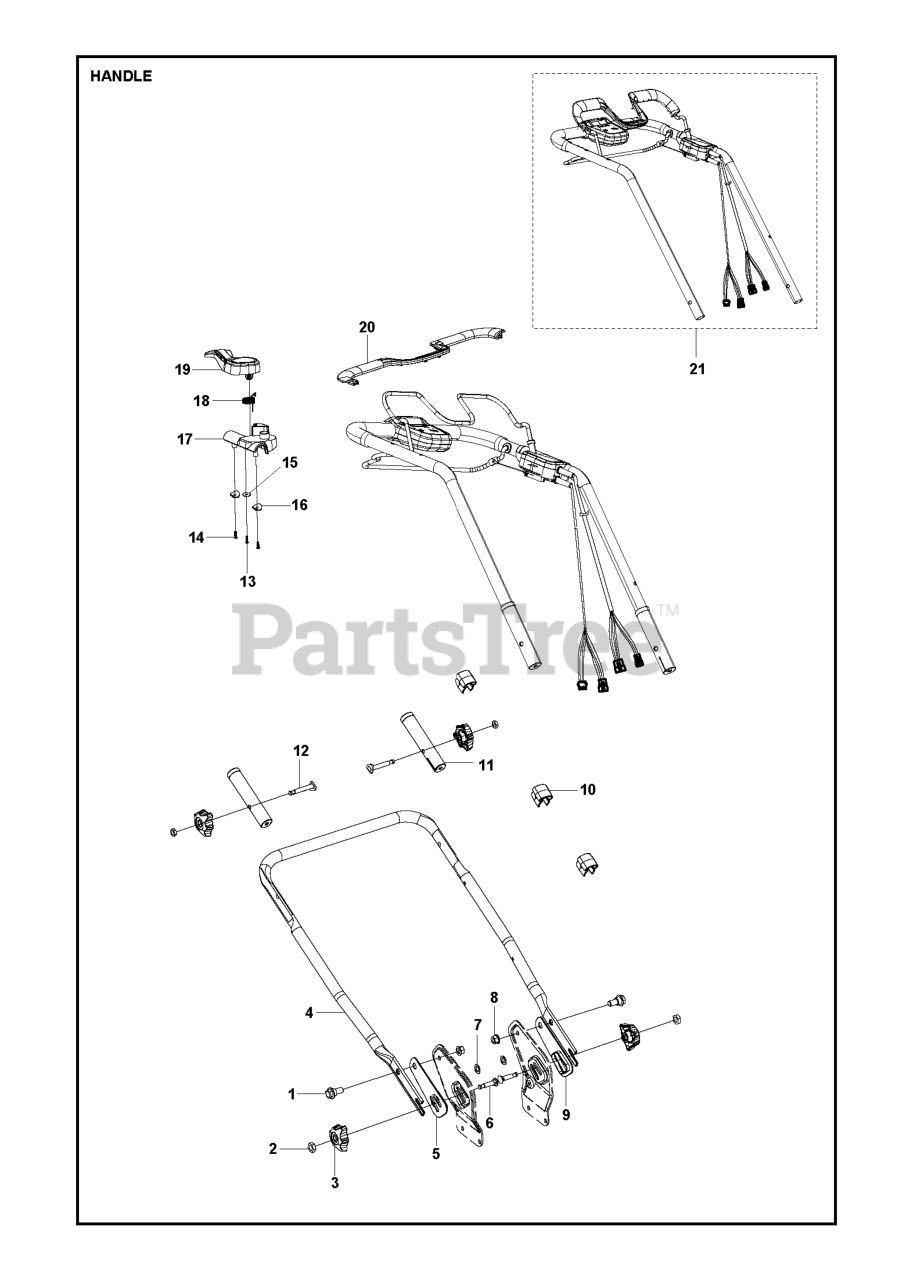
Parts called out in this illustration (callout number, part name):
2	HEXAGON NUT #26800502301
3	KNOB #25341500101
4	HANDLEBAR LOWER
5	PLATE RIGHT
7	SPACER RING
8	LOCKING BOLT M8,GB6187.1 #2680
9	PLATE LEFT
10	HOLDER CABLE
17	HOLDER BAIL STOP SOLUTION HOLD
18	TORSION SPRING
19	COVER BAIL STOP SOLUTION
20	COVER BAIL ARM COVER
21	HANDLE KIT DAYE# 90000305301
